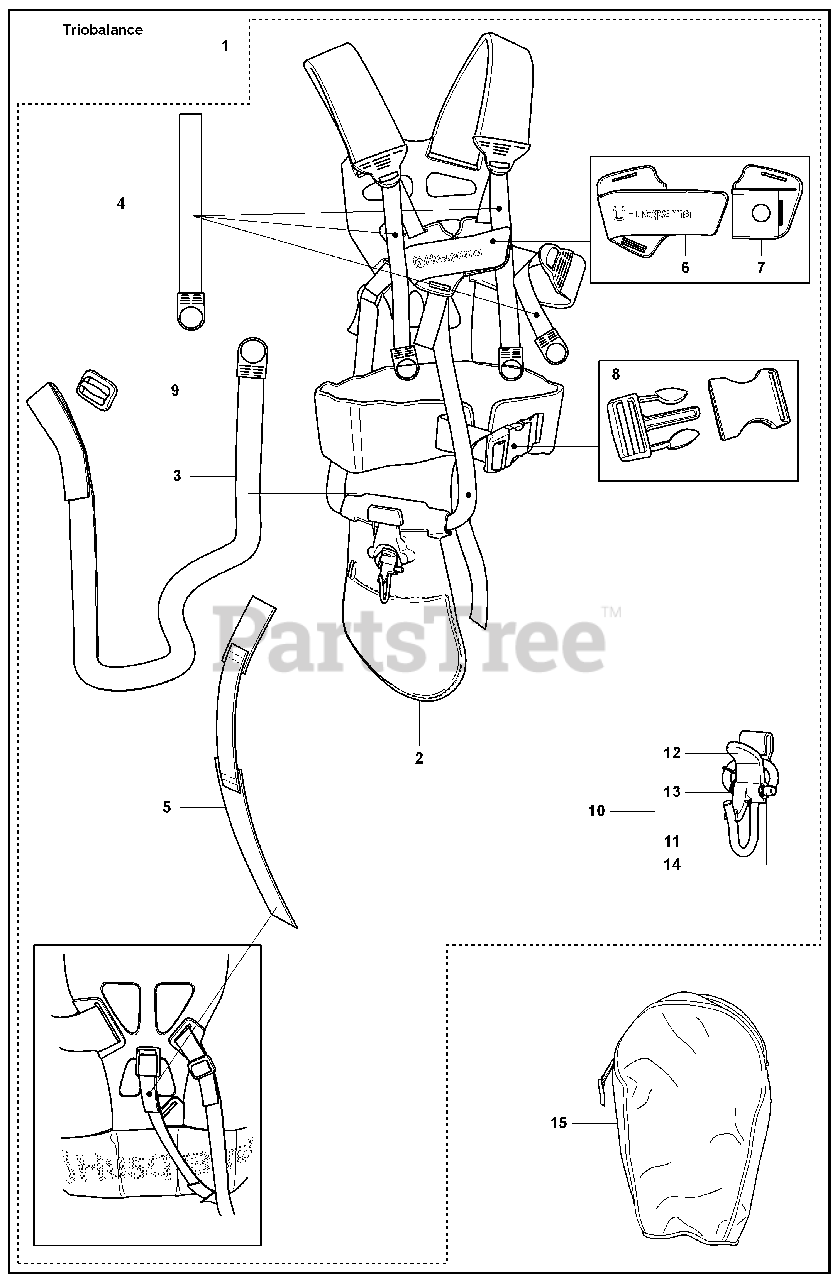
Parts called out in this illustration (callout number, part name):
1	RP HARNESS TRIO BALANCE
6	FRONT PIECE
7	FRONT PIECE
9	RP CLIP
10	WELT HOOK
11	HOOK
12	CATCH *
13	SPRING
15	TOOL BAG
